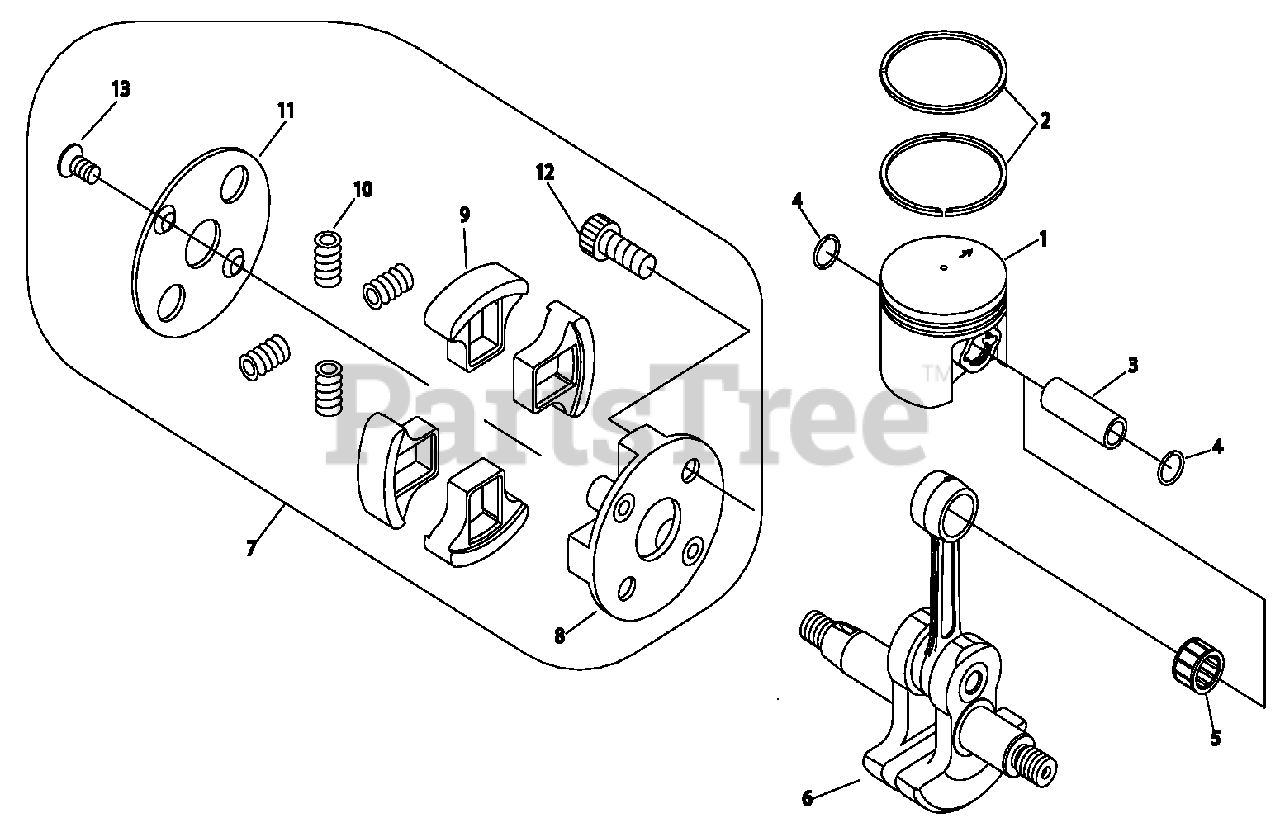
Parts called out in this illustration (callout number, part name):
1	PISTON
2	RING, PISTON
3	PIN, PISTON
4	RING, SNAP
5	BEARING, NEEDLE
6	CRANKSHAFT
7	CLUTCH ASSY
8	BOSS, CLUTCH
9	SHOE, CLUTCH
10	SPRING, CLUTCH
11	PLATE, CLUTCH
12	BOLT, CLUTCH
13	BOLT 5
